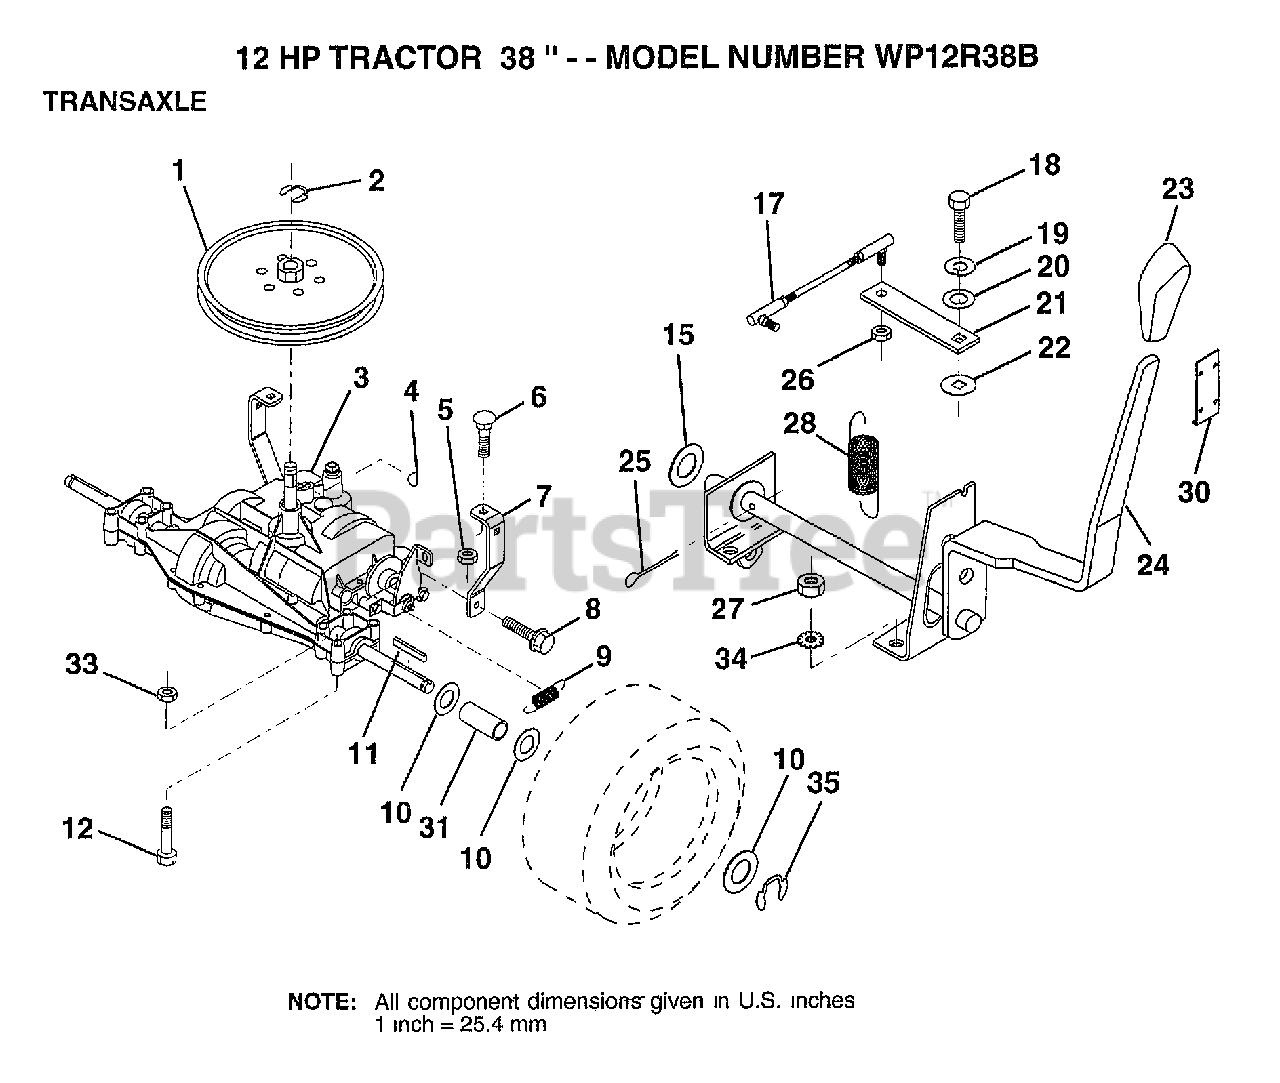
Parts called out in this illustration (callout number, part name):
1	PULLEY
3	TRANSAXLE.6SP.D
6	BOLT
7	"STRAP,TORQUE"
8	SCREW
10	WASHER
11	SQUARE KEY
12	BOLT
17	"LINK,SHIFT"
19	LOCKWASHER
20	WASHER LT
21	"ARM,SHIFT"
22	WASH-SHFT PLT LT
23	"KNOB,SHT CONTROL"
25	PIN COTTER 1/8
26	NUT.LOCK.5/16-24
28	"SPRING,EXT"
30	KNOB RETAINER
31	SPACER
34	LOCKWASHER.5/16.E
35	E-RING LT
